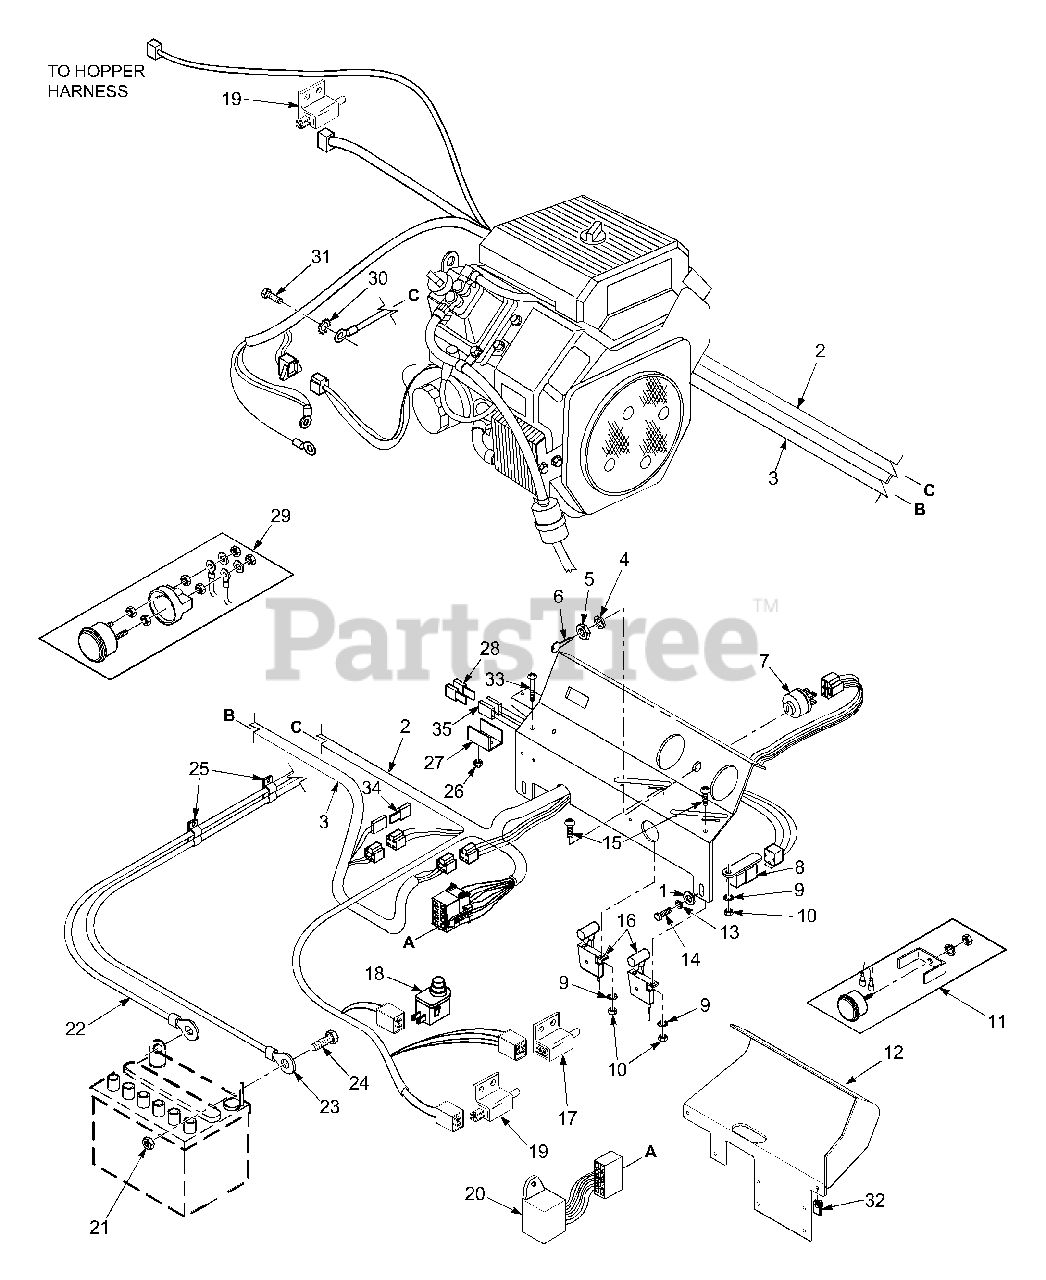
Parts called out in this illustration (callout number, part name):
1	Flatwasher, 5/16-.375 x .875 x .083
2	Wire Harness, SCR
3	Wire Harness, Hopper
4	Lockwasher, Internal 5/8"
5	Nut, 5/8-32 Special
6	Key & Ring
7	Keyswitch w/hardware
8	Relay
9	Lockwasher, #10 external tooth
10	Nut, #10-32 UNF
11	Hour Meter
12	Instrument Panel, Lower
13	Lockwasher, 5/16
14	Bolt, Hex Head 5/16-18 x 1"
15	Screw, #10-32 x 1/2"
16	Control Cable
17	Switch, PTO
18	Switch, Seat
19	Switch, Brake & Hopper
20	Interlock Module
21	Nut, 1/4-20
22	Battery Cable, Black
23	Battery Cable, Red
24	Bolt, Hex Head 1/4-20 x 1/2"
25	Cable Clamp, Double
26	Nut, Elastic Stop #10
27	Bracket, Fuse Holder
28	Fuse, 20 Amp
29	Ammeter
30	Lockwasher, 3/8"
31	Bolt, Hex Head
32	U-Nut, 5/16-18
33	Screw, #10-32 x 1-1/2"
34	Fuse, 15 Amp
35	Fuse Holder W/Fuse & Connector
